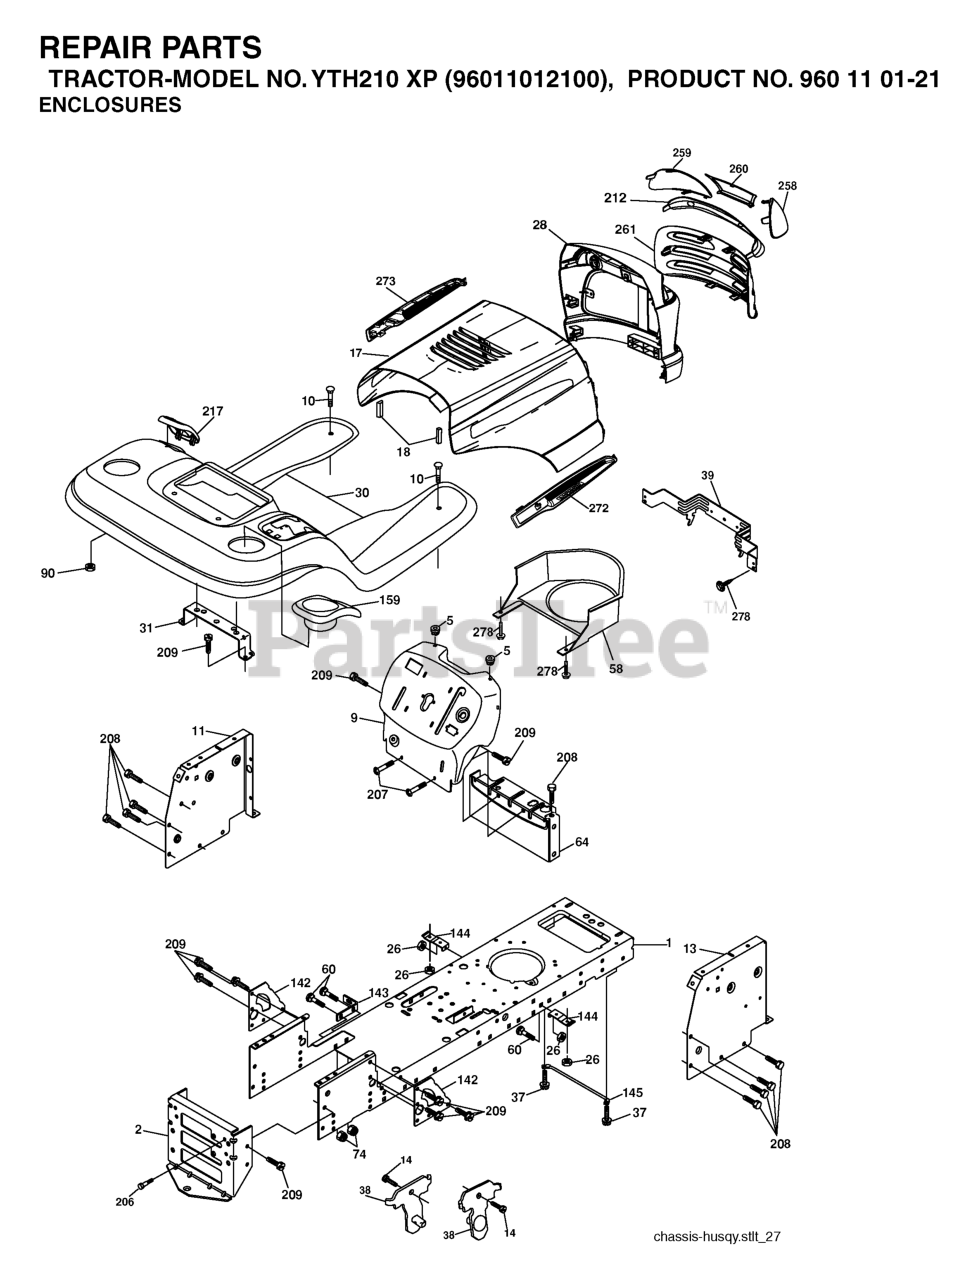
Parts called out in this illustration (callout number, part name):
1	CHASSIS STAMPING
2	DRAWBAR, 12GA
5	BUMPER.RUBBER.HOOD
9	DASH.SLKSCR.STL.PL.E.NA.WHM.CE
10	BOLT D
11	PANEL.DASH.LH.LTX
13	PANEL ASM, DASH RH
17	VENT.HOOD.LASER.III
18	BUMPER.HOOD.LARGE.1.75"
26	NUT
30	FENDER
31	BRACKET.SUPPORT.FENDER
37	Screw 5/16-18 x 1/2 Hex, Self Tapping 5/16-18 x 1/2
38	BRACKET.ASM.PIVOT.MOWER.REAR
39	BRACKET PIVOT LASER
60	Bolt - Rd. Hd. Sq. Neckiage 3/8 16 x 3/4
64	DASH LOWER
90	NUT.PUSH.3/16
142	PLATE REINFORCEMENT
143	BRACKET, SWAYBAR CHASSIS
144	BRKT, FOOT REST
145	ROD PIVOT CHASSIS/HOOD
159	CUPHOLDER
206	SHOULDER BOLT 5/16-18TT
207	SCREW, 5/16-18 X 1/2
208	SCREW 3/8-16X1/2
209	SCREW, 3/8-16X3/4
212	INSERT.LENS.REFLECTIVE
217	CONSOLE FUEL WINDOW
258	LENS LH
259	LENS LH
260	COVER.LENS.HUSQ.LASER
272	VENT.HOOD.LASER.
273	VENT.HOOD.LASER.
278	SCREW
